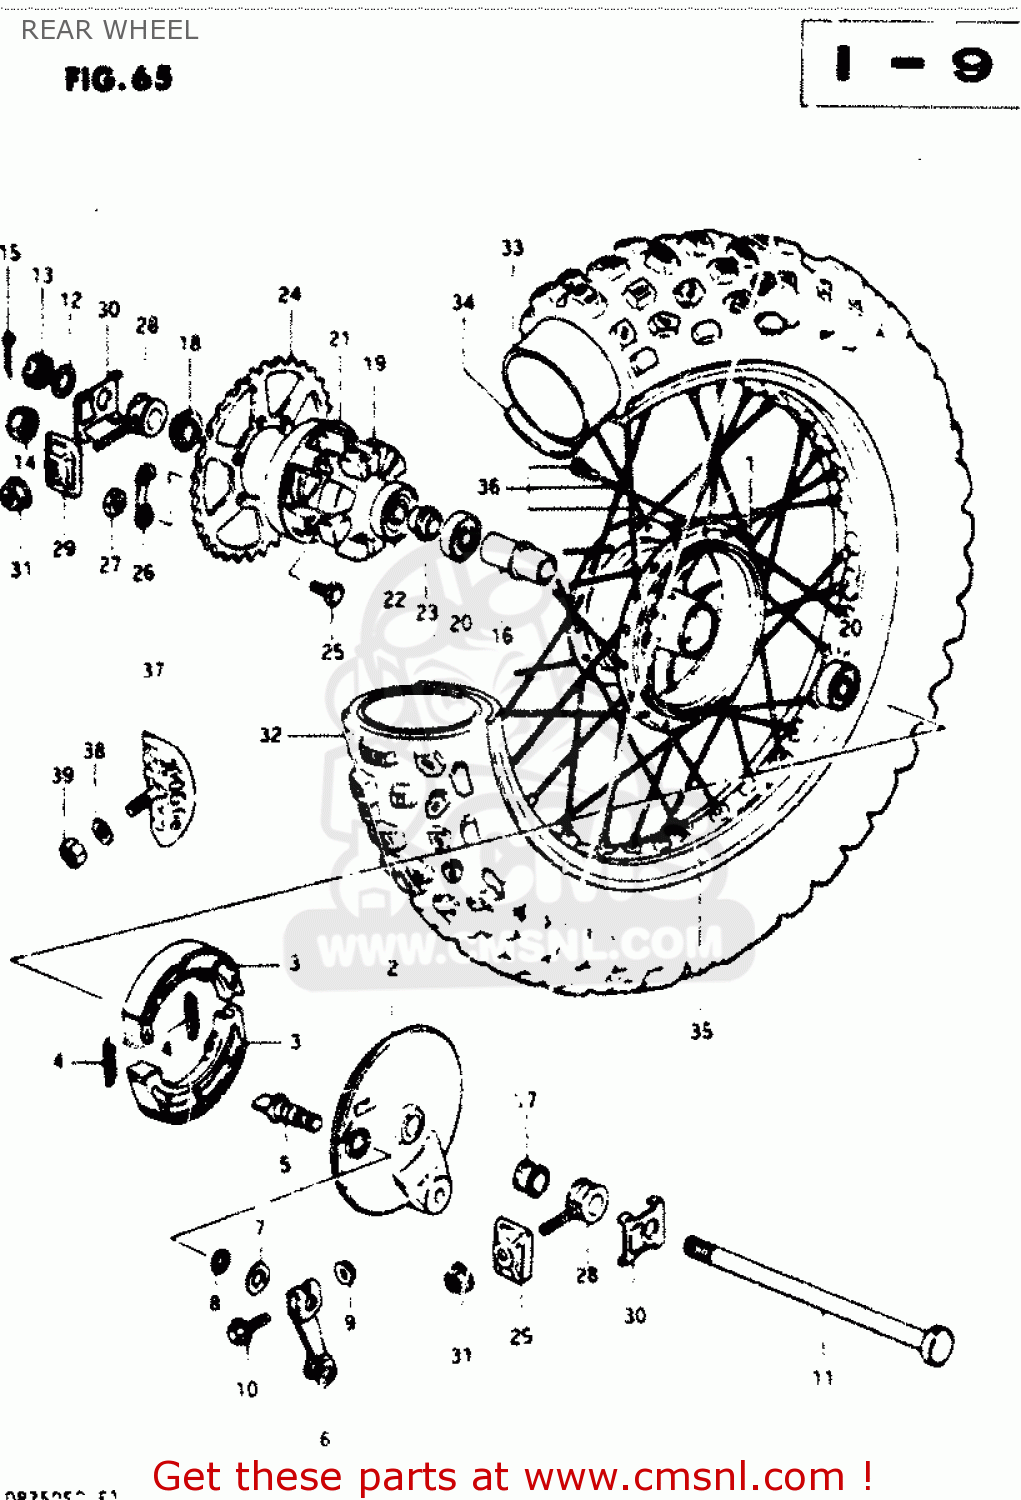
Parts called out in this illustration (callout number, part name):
1	DRUM,REAR HUB
2	PANEL,REAR HUB
3	SHOE,BRAKE
4	SPRING(L:34)
5	CAM,FRONT BRAKE
6	LEVER,REAR BRAKE CAM
7	WASHER (14.5X22X1.6)
8	O-RING (D:2.4 ID:13.8)
9	NUT
10	BOLT 6X35
11	AXLE,REAR
12	WASHER
13	NUT
14	NUT
15	PIN,COTTER
16	SPACER,REAR HUB BEARING
17	SPACER,REAR AXLE,RIGHT
18	SPACER,REAR AXLE
19	CUSHION,REAR DRUM
20	BEARING
21	DRUM,REAR SPROCKET MOUNT
22	BEARING
23	SPACER,REAR HUB BEARING
24	SPROCKET,RR(NT:42)
25	BOLT
26	WASHER
27	NUT
28	ADJUSTER,CHAIN
29	PLATE,CHAIN ADJUSTER
30	WASHER,CHAIN ADJUSTER GUIDE
31	NUT
32	TIRE, REAR (4.00X18)
33	TUBE ASSEMBLY,WHEEL,INNER
34	PROTECTOR,WHEEL,INNER
35	RIM, WHEEL (215X17AL) (GOLD)
36	SPOKE ASSY, REAR
37	STOPPER,BEAD
38	WASHER
39	NUT
